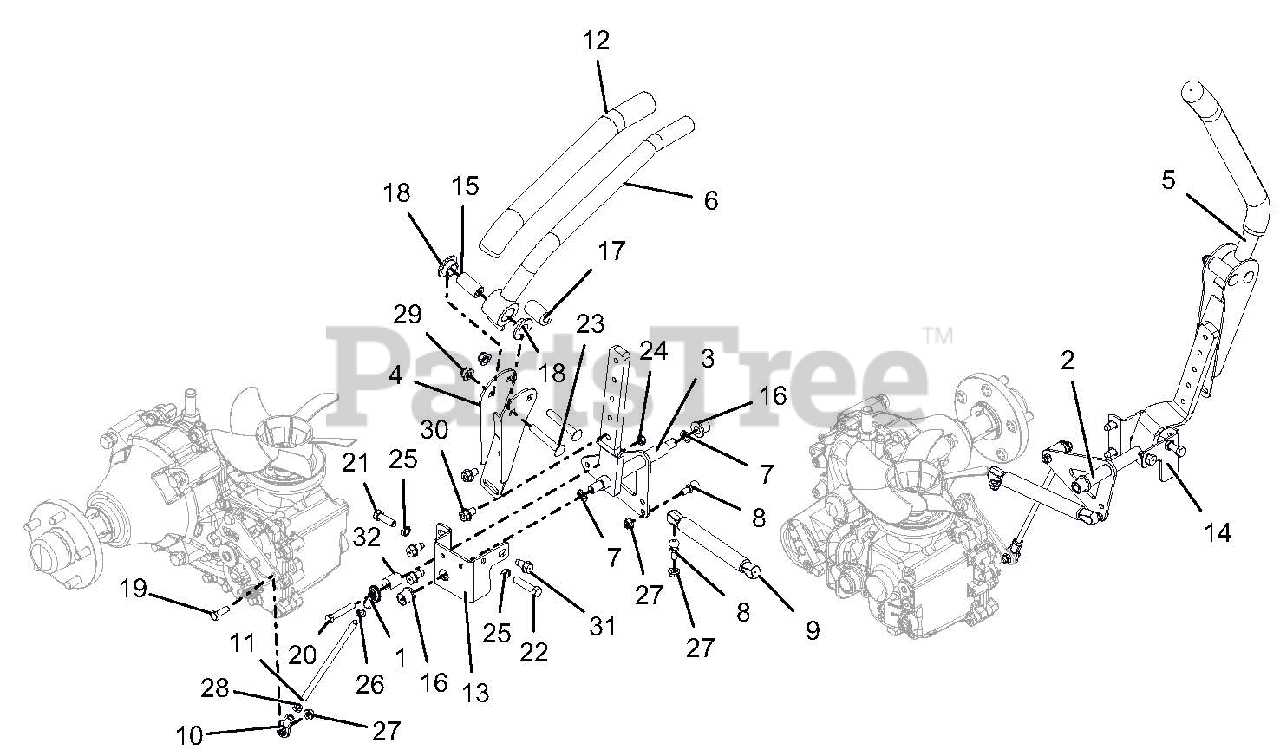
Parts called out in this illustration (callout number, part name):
1	ALIGNABALL, 5/16 RH THREAD
2	WLDMT, LH LOWER CONTROL ARM
3	WLDMT, RH LOWER CONTROL ARM
4	WLDMT, UPPER ADJUSTABLE CONTROL ARM
5	WLDMT, LH CONTROL HANDLE
6	WLDMT, RH CONTROL HANDLE
7	WAVE WASHER .531X.781X.125 FH
8	STUD-BALL
9	DAMPER,
10	ALIGNABALL, 5/16 LH THREAD
11	ROD, STEERING
12	GRIP, HANDLEBAR
13	BRKT, RH CONTROL ARM STOP
14	BRKT, LH CONTROL ARM STOP
15	SPCR, STEERING ARM
16	BHSG-FLG .500X.750X.750X.125
17	BSHG, ECCENTRIC .328 X .750 X 1.625
18	BSHG, FLANGE .762 X 1.48 X .44 NYLON
19	BLT-HEX .31-18X1.00 GR5 YWZC
20	BLT-HEX .31-18X2.00 GR5 YWZC
21	BLT-HEX .38-16X1.25 GR5 YWZC
22	BLT-HEX .38-16X1.75 GR5 YWZC
23	BLT-RHDSSQNK .38-16X2.50 G5YZ
24	NUT-LK-CTR .31-18 YWZC
25	NUT, JAM .375-16 YWZC
26	NUT-JAM
27	NUT, LK-TOP-FLG .312-18 YWZC
28	NUT, JAM -LH .31-24 YWZC
29	NUT-LK-NYL-FLG .38-16 YWZC
30	BLT-SERHFWH .38-16X.62 YWZC
31	SCR-TAP .38-16X.75 HWH TR YWZ
32	ECCENTRIC
